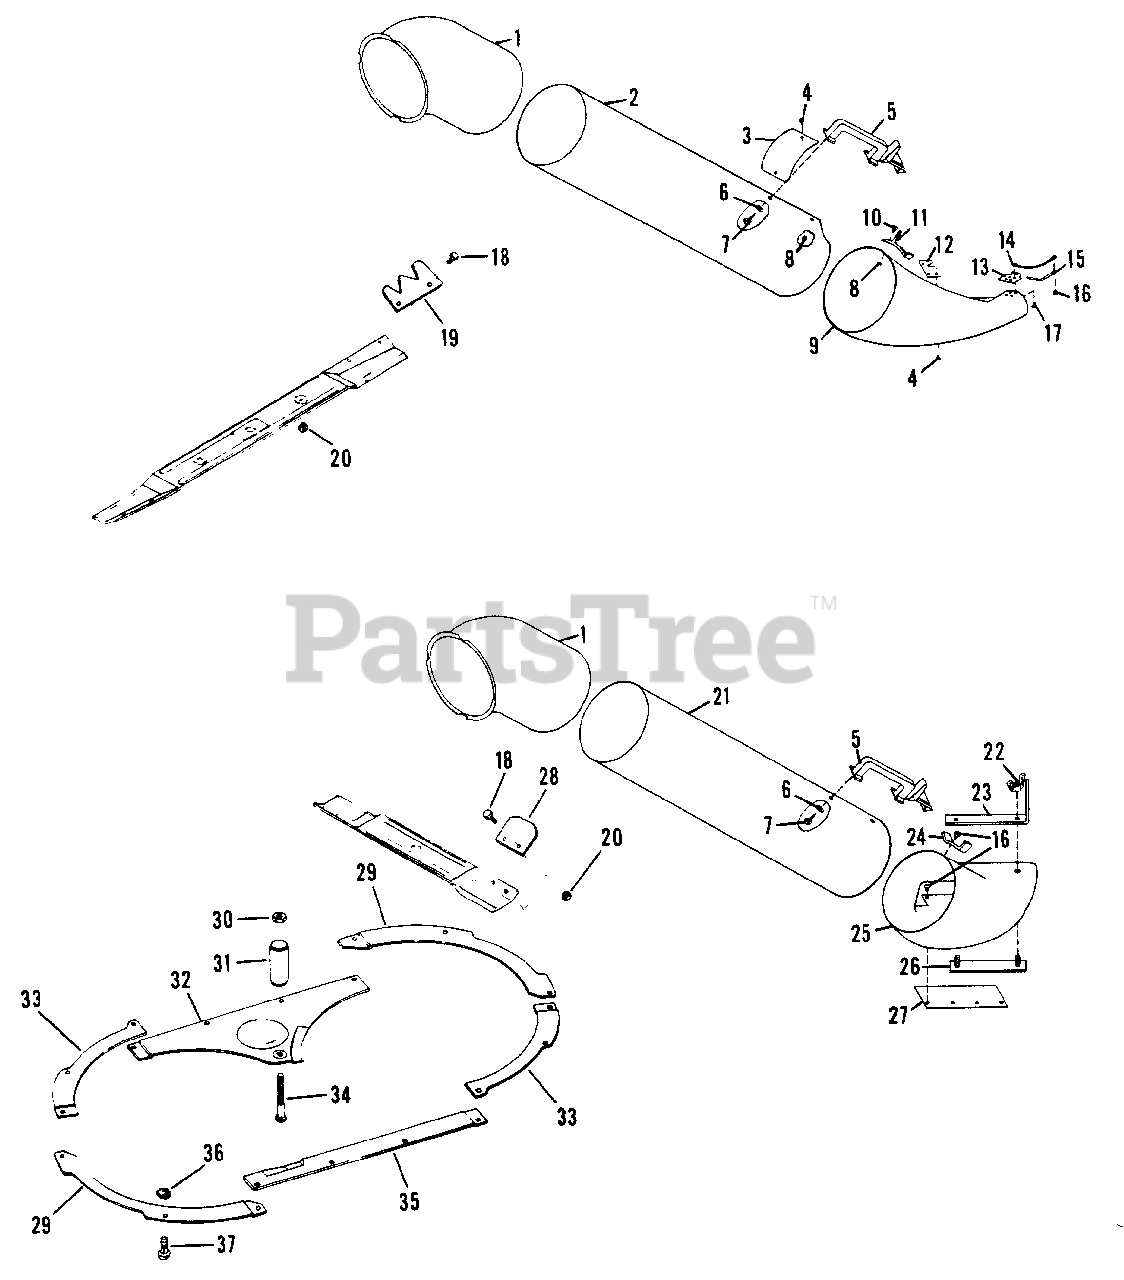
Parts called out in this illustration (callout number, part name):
1	Boot, Bagger
2	Tube, Bagger
3	Plate
4	Rivet, Pop Domed
5	Handle, Tube
6	Washer
7	Screw, Tapping
8	Washer, Flat .188x.562x.049
9	Boot, 32" Mower
10	Rivet, Pop Domed
11	Retainer, Tube
12	Support, Boot
13	Bracket, Boot
14	Lanyard
15	Pin, Pull
16	Rivet
17	Rivet, Pop Domed
18	Bolt, Hex 5/16-24x.75
19	Vane
20	Nut, Lock 5/16-24 Gr. C
21	Tube, Bagger
22	Nut, Wing 5/16-18
23	Strap, Boot
24	Clip, Tube Retainer
25	Boot, 38" Mower
26	Weldment, Boot Strap
27	Extension, Chute
28	Assembly, Vane(Set of 2)
29	Flange, Long Curve
30	Nut, Lock 1/2-13
31	Spacer
32	Flange, Rear
33	Flange, Short Curve
34	Bolt, 1/2-13x4.25 Rd Hd Sq Nk
35	Flange, Front
36	Nut, Lock 1/4-20
37	Bolt, 1/4-20x.625 Rd Hd Sq Nk
